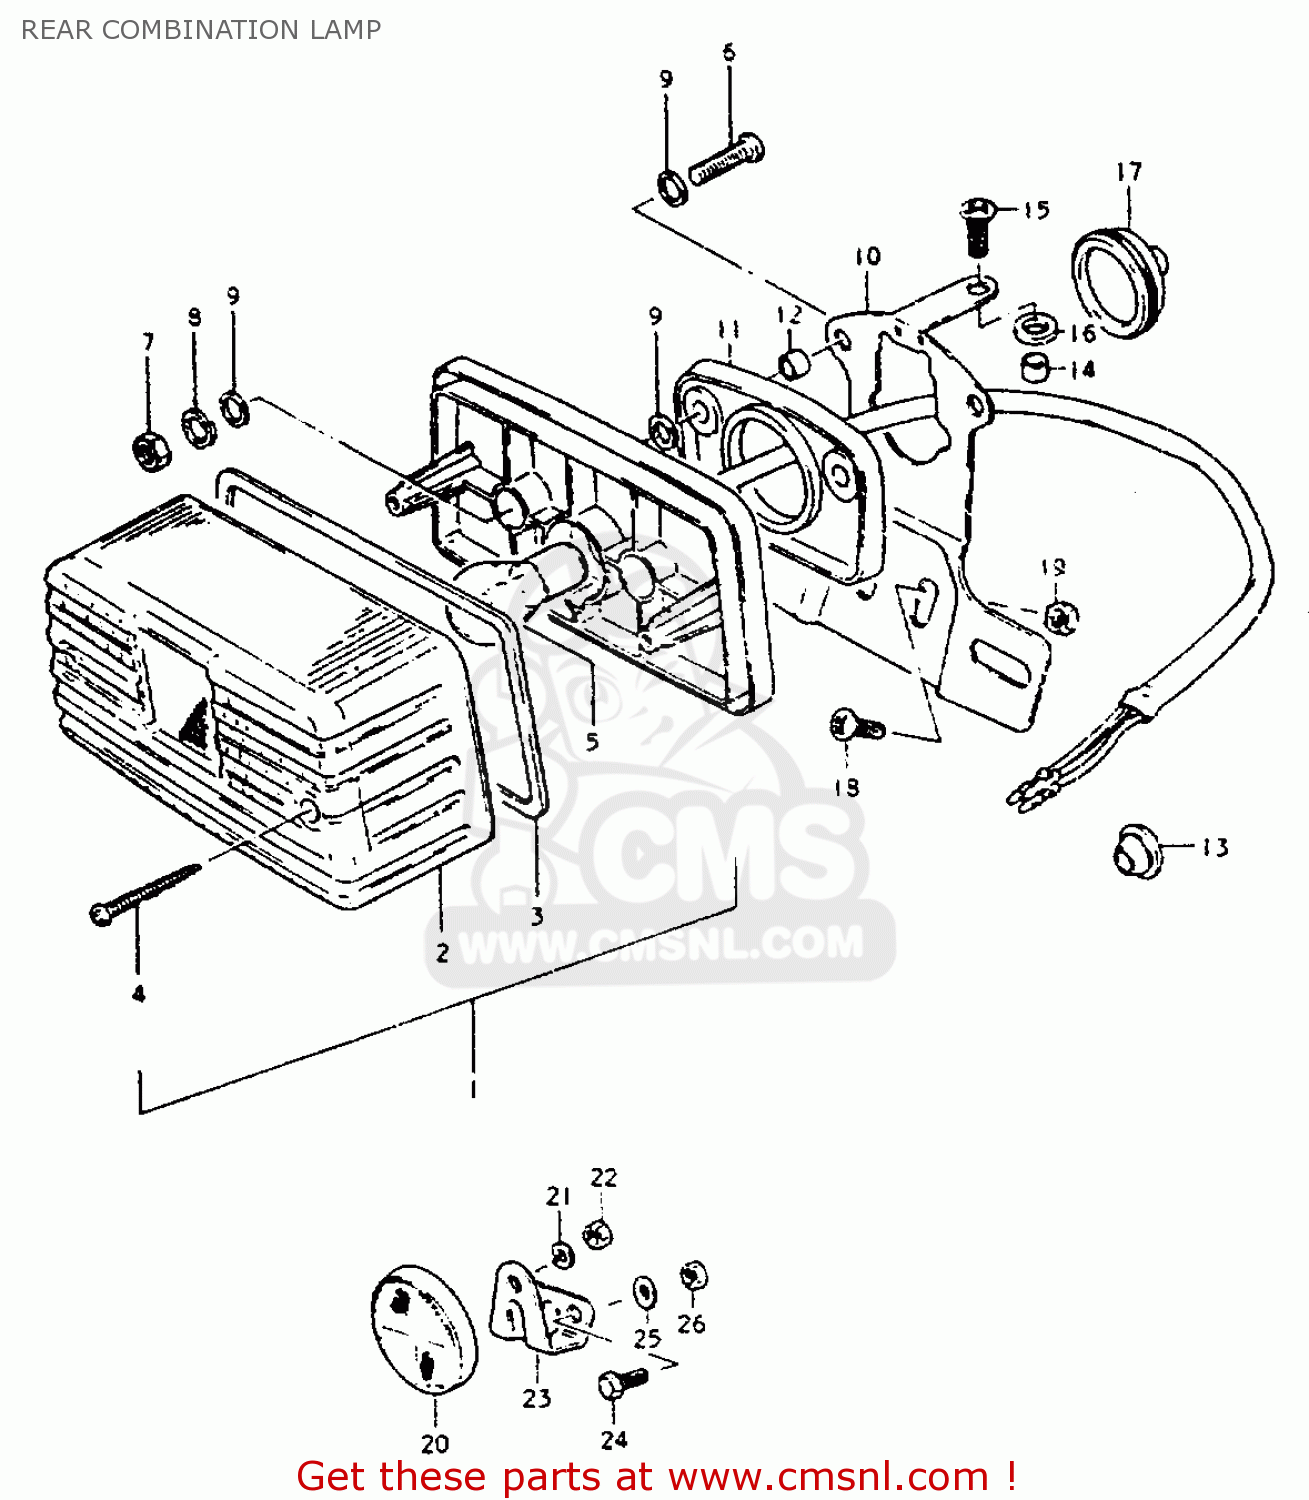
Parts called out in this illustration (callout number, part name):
1	LAMP UNIT, TAIL
2	LENS
3	GASKET (NAS)
4	SCREW
5	BULB (6V,21/5W)
6	SCREW
7	NUT
8	LOCK WASHER
9	WASHER
10	BRACKET ASSY
11	CUSHION
12	SPACER
13	GROMMET
14	SPACER (6.1X8X5.2)
15	SCREW (6X15)
16	CUSHION
17	GROMMET
18	SCREW
19	NUT
20	REFLECTOR,REFLEX
21	LOCK WASHER
22	NUT
23	BRACKET
24	BOLT
25	WASHER
26	NUT
